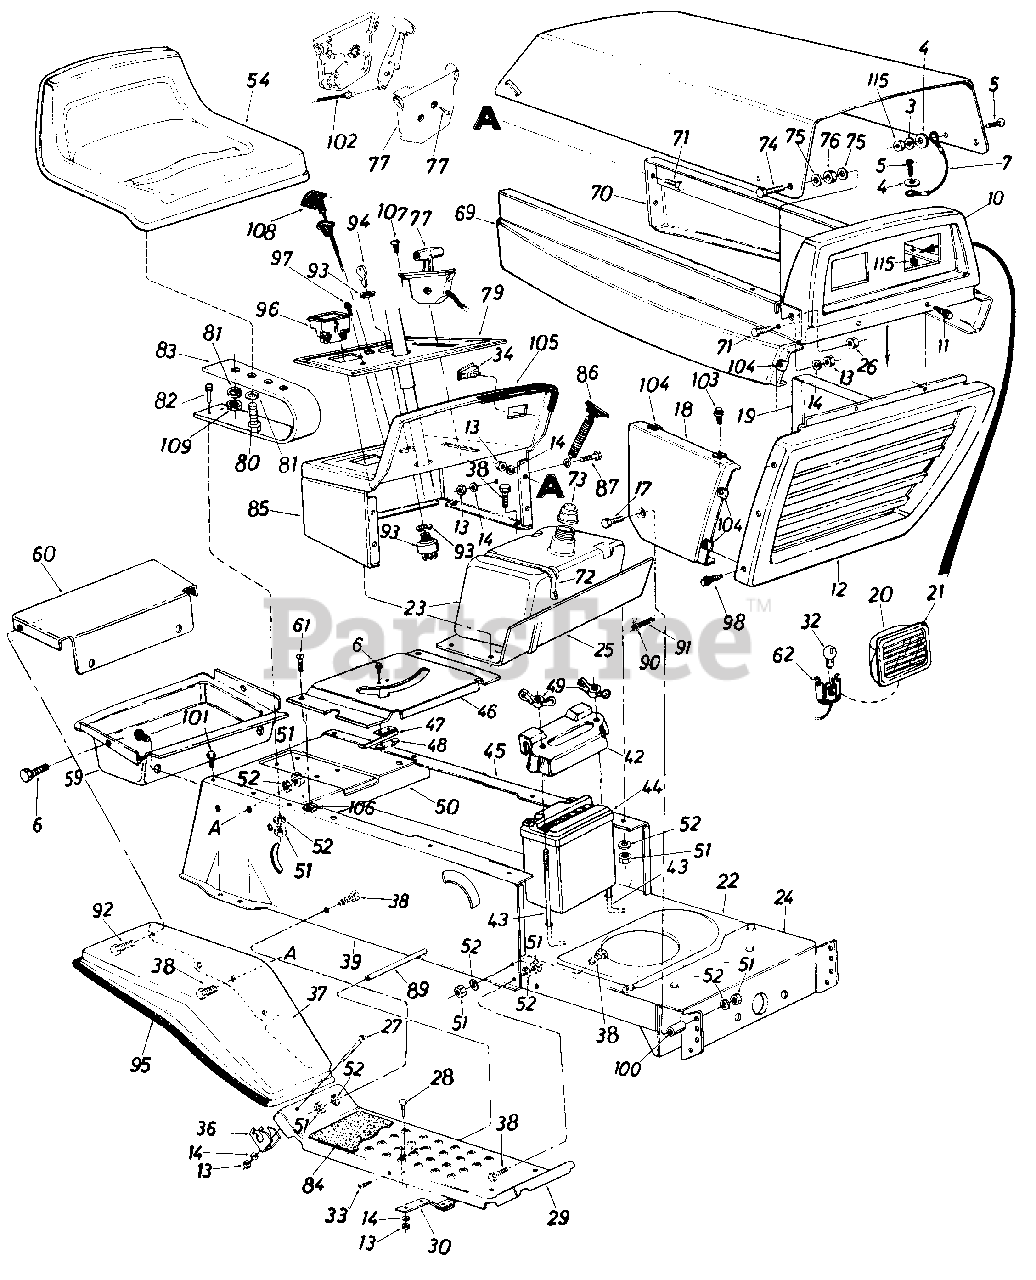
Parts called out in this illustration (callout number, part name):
3	L-Wash. #10 I.D.
4	Fl-Wash. .25" I.D. x .62" O.D.
5	Truss Scr. #10-24 x .375" Lg.
6	Truss Hd. Scr. #10-24 x .50" Lg.
7	Hood Stop
10	Front Grille Upper Ass'y.
11	Hex AB-Tap Scr. #8 x .50" Lg.
14	L-Wash. 1/4" I.D.
17	Hex Bolt 5/16-18 x 1.50" Lg.
18	R.H. Lower Side Panel
19	L.H. Lower Side Panel
20	Headlight Housing
21	Headlight Lens
22	Lower Frame
23	Fuel Tank
24	Front Pivot Brkt.
25	Fuel Tank Support
26	Hex Cent. L-Nut 3/8-16 Thd.
27	Truss Hd. Scr. 1/4-20 x 1.75" Lg.*
28	Carriage Bolt 1/4-20 x .62" Lg.*
29	Running Board
30	Blade Brake Ass'y.
32	Head Lampt
33	Truss Mach. Scr. 5/16-18 x .75" Lg.
34	Light Switch
36	Fender Clamp
39	R.H. Side Frame
42	Battery Cover
43	Battery Hold Down Rod
44	12-V Battery
45	L.H. Side Frame
46	Transmission Panel
47	Reverse Safety Switch
48	Insulator Nut Plate
49	Wing Nut 1/4-20
50	Hitch Plate
51	Hex Nut 5/16-18 Thd.
52	L-Wash. 5/16" I.D.
54	Seat Ass'y.
59	Tool Tray
62	Head Lamp Socket
69	Side Panel-R.H.
70	Side Panel-L.H.
71	Hex Bolt 1/4-20 x .62" Lg.
72	Tie Strap
73	Fuel Cap Gauge
74	Hex Bolt 3/8-16 x 1.00" Lg.
75	Fl-Wash. .380" I.D. x 1.00" O.D.
76	Rubber Wash. .33" I.D. x .87" O.D.
77	Throttle Control Box Ass'y.
79	Dash Panel Insert
80	Hex Bolt 1/2-13 x 1.00" Lg.
81	L-Wash. 1/2" I.D.
82	Hex Bolt 5/16-18 x 1.00"
83	Seat Spring
84	Foot Pad
87	Hex Bolt 1/4-20 x .50" Lg.
89	Running Board Rod
90	Hose Clamp
91	Fuel Line
92	Thread Rolling Scr. 1/4-20 x .50" Lg.
93	Ignition Switch
94	Ignition Key
95	Trim Strip
96	Ammeter
97	Hex "AB"-Tap Scr. #8 x .50" Lg.
98	Hex AB-Tap #10 x .50" Lg.
100	Spacer .344" I.D. x 1.0" O.D. x .75" Lg.
101	Hex Wash. Hd. AB-Tap Scr. 5/16 x .75" Lg.
102	Throttle Control Wire
103	Hex Wash. Hd. Self-Tap Scr.
104	Speed Nut #10Z
105	Trim Strip-15"
106	Speed Nut #10Z
107	Truss Mach. AB-Tap Scr. #10 x .50" Lg.
108	Choke Control 29" Lg.
109	Hex Nut 1/2-13 Thd.
